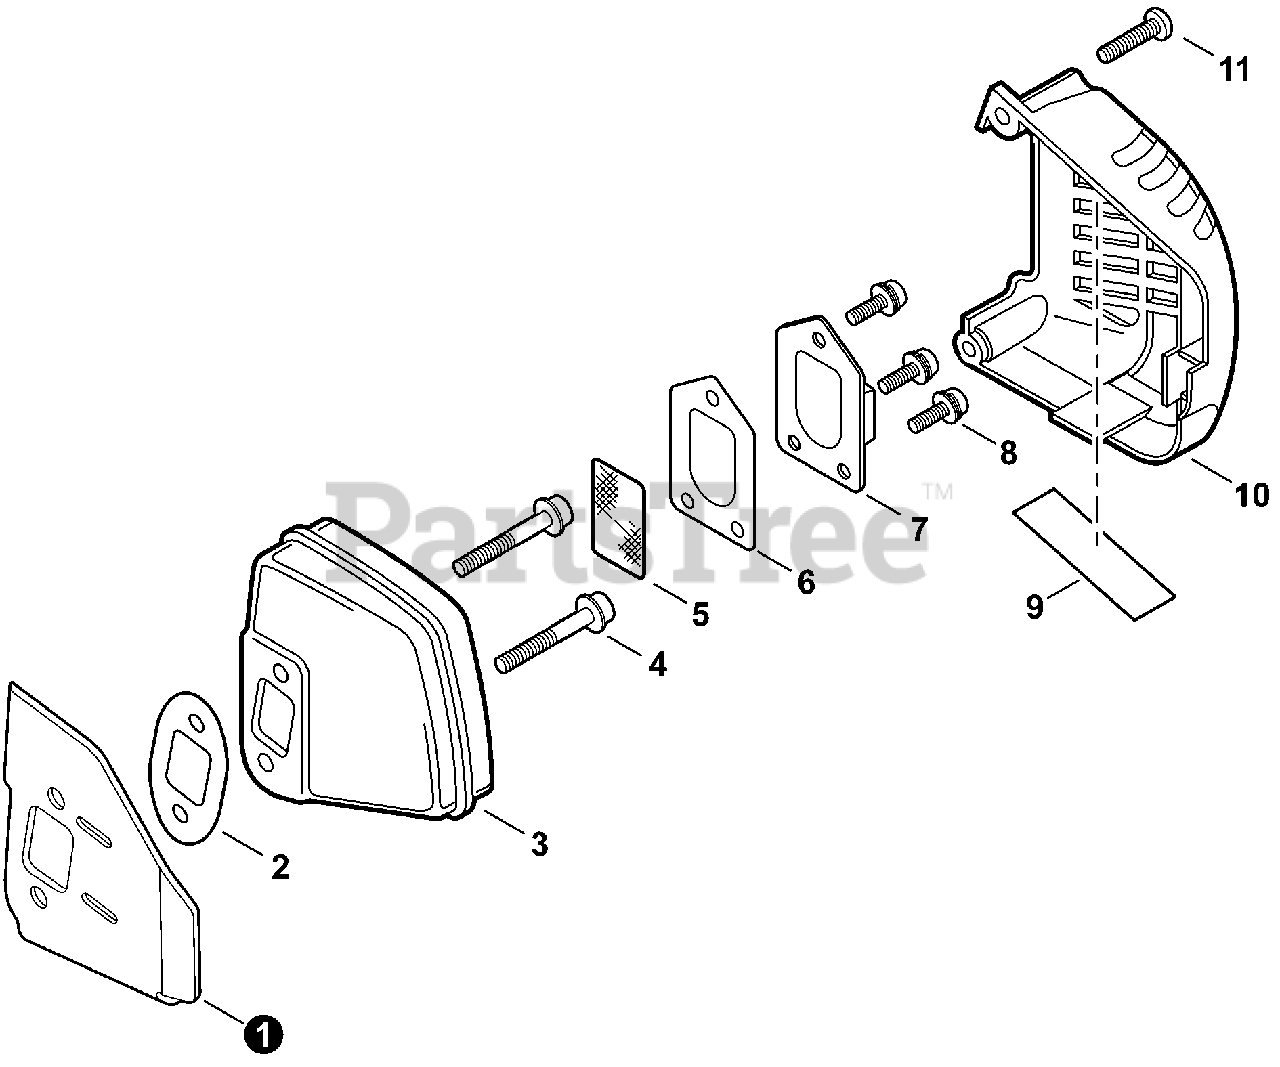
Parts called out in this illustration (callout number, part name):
1	HEAT SHIELD, EXHAUST
2	GASKET, EXHAUST
3	MUFFLER
4	BOLT, FLANGE HSH 5×45
5	SCREEN, SPARK ARRESTER
6	GASKET, EXHAUST
7	GUIDE, EXHAUST
8	SCREW 4×10
9	SHIELD, HEAT
10	COVER, MUFFLER
11	SCREW 4×16
